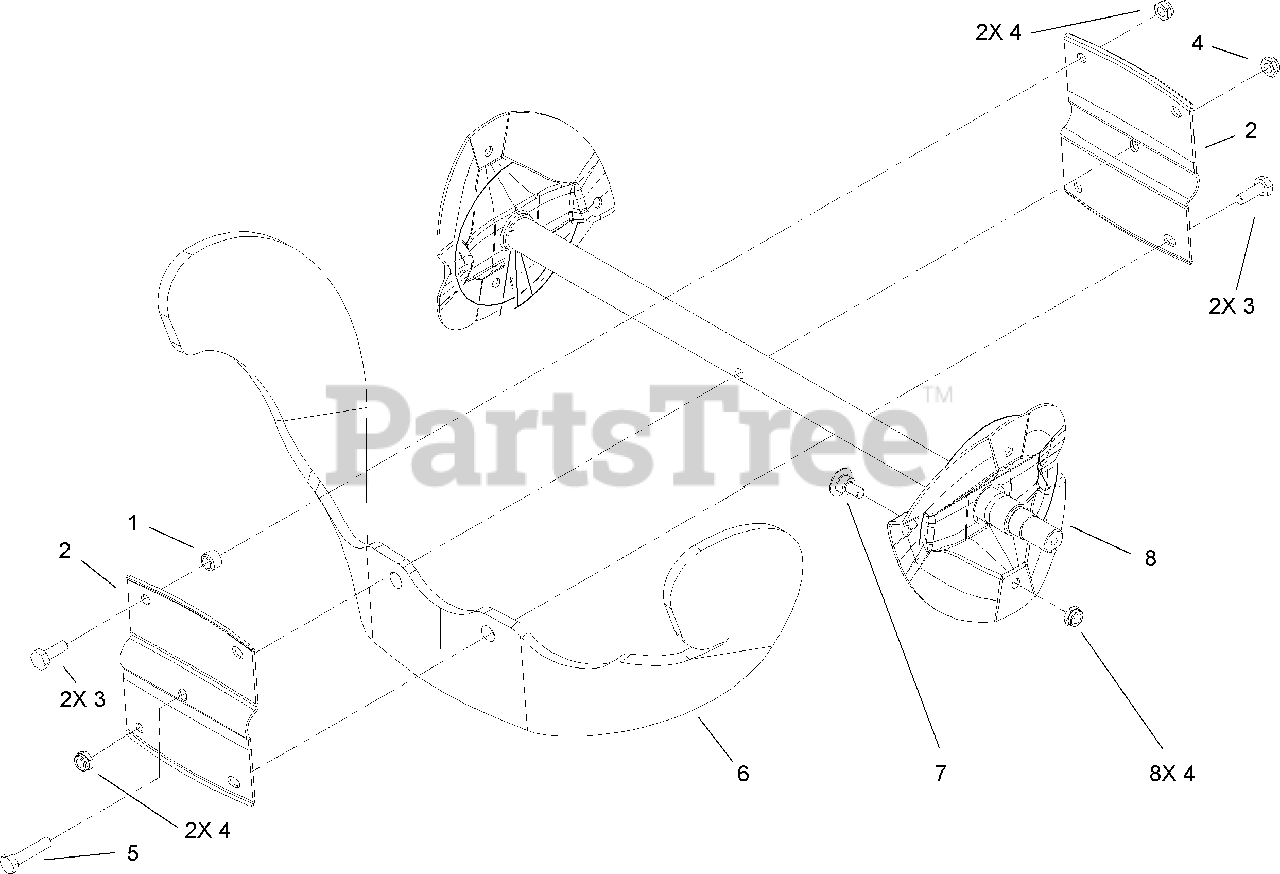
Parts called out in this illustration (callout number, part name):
1	SPACER-BLADE, ROTOR
2	HALF-ROTOR
3	SCREW-HH
4	NUT-LOCK, NI
5	SCREW-HH
6	BLADE-ROTOR
7	SCREW
8	ROTOR
